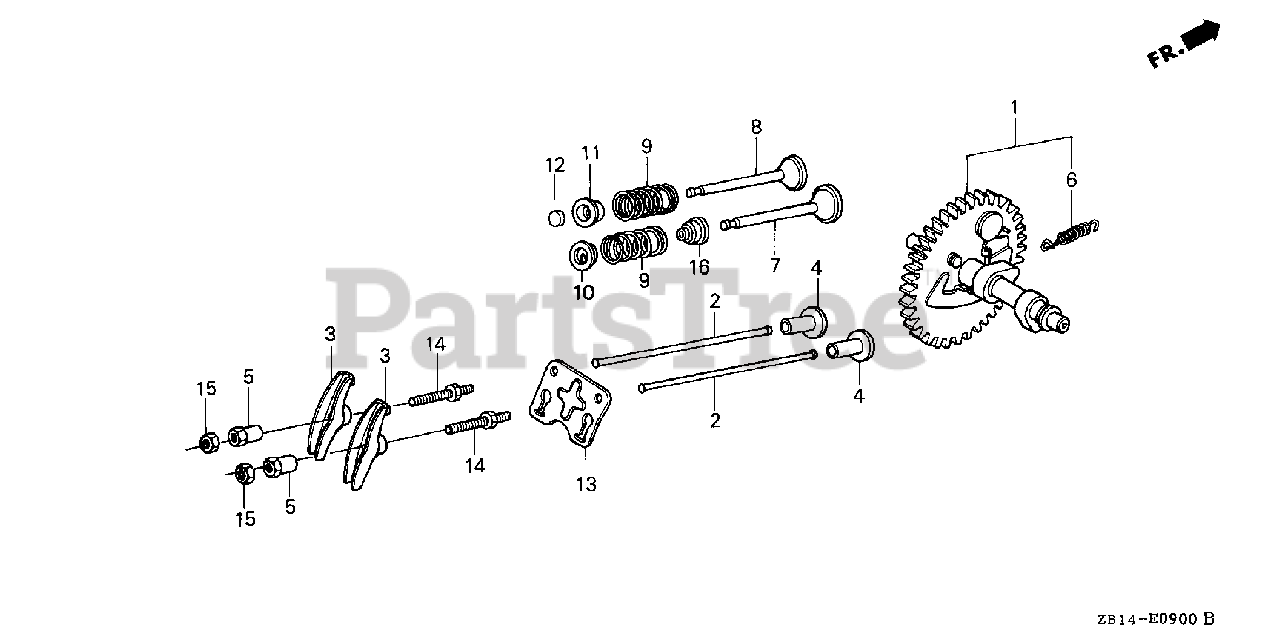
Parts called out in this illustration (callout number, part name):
1	CAMSHAFT ASSY.
2	ROD, PUSH
3	ARM, VALVE ROCKER
4	LIFTER, VALVE
5	PIVOT, ROCKER ARM
6	SPRING, WEIGHT RETURN
7	VALVE, IN.
8	VALVE, EX.
8	VALVE, EX. (STELITE)
9	SPRING, VALVE
10	RETAINER, IN. VALVE SPRING
11	RETAINER, EX. VALVE SPRING
12	ROTATOR, VALVE
13	PLATE, PUSH ROD GUIDE
14	BOLT, PIVOT
14	BOLT, PIVOT (8MM)
15	NUT, PIVOT ADJUSTING
